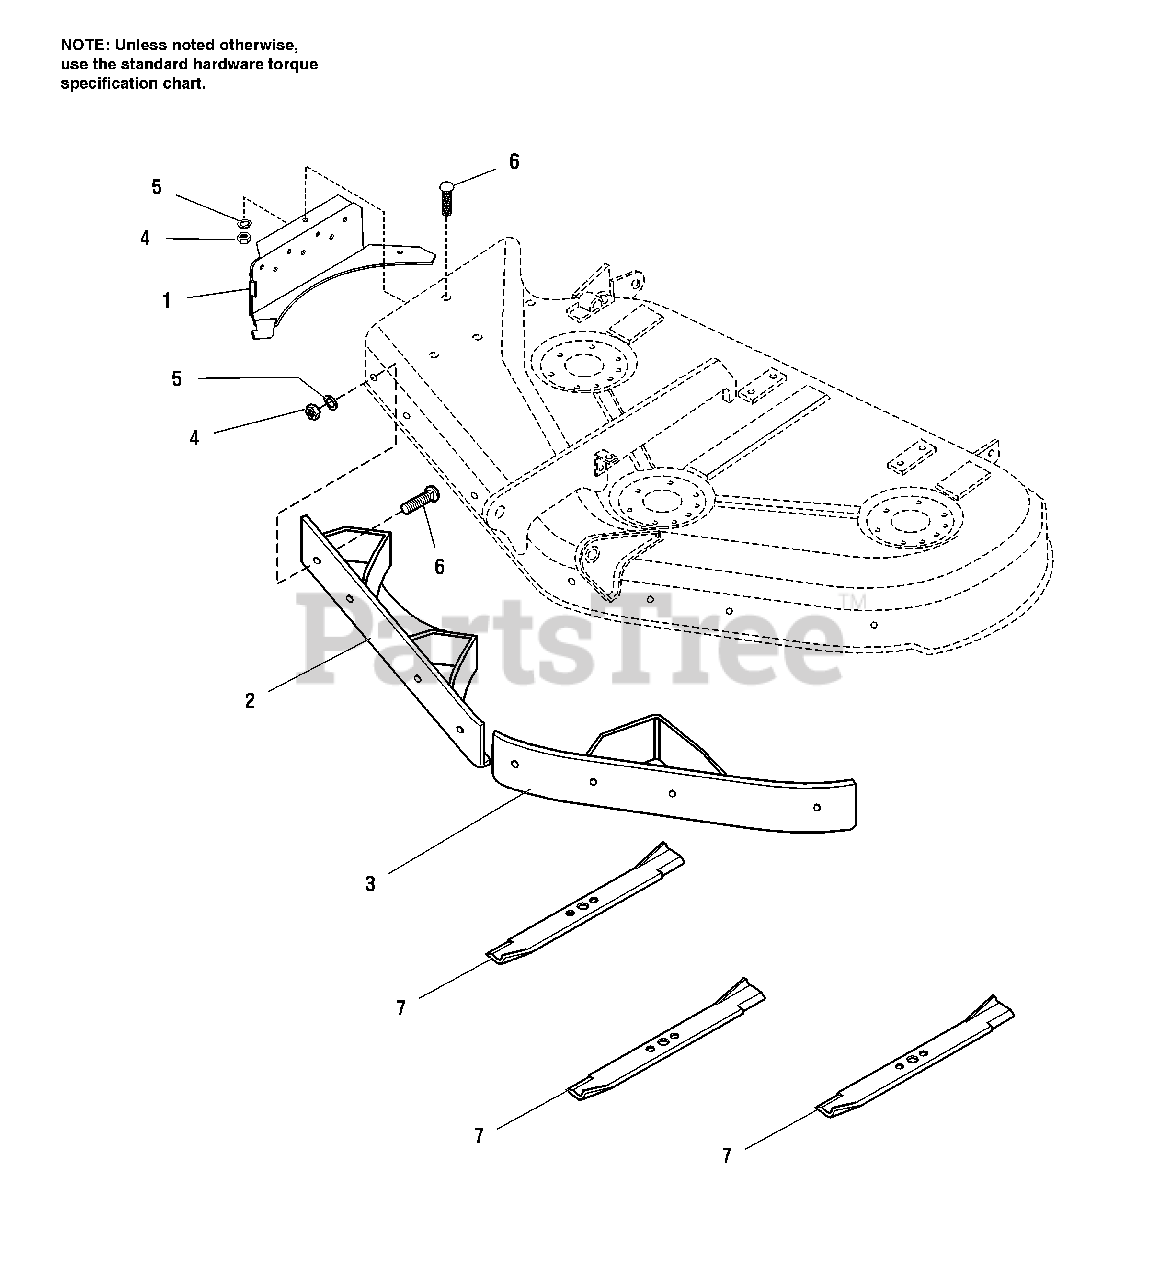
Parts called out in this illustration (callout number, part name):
1	PLATE, Discharge Closure
2	BAFFLE Assembly, RH 44"
3	BAFFLE Assembly, LH 44"
4	NUT, Hex 5/16-18
5	LOCK WASHER, 5/16
6	BOLT, Carriage 5/16-18 x 0.625
7	BLADE, Mulch for 44"
